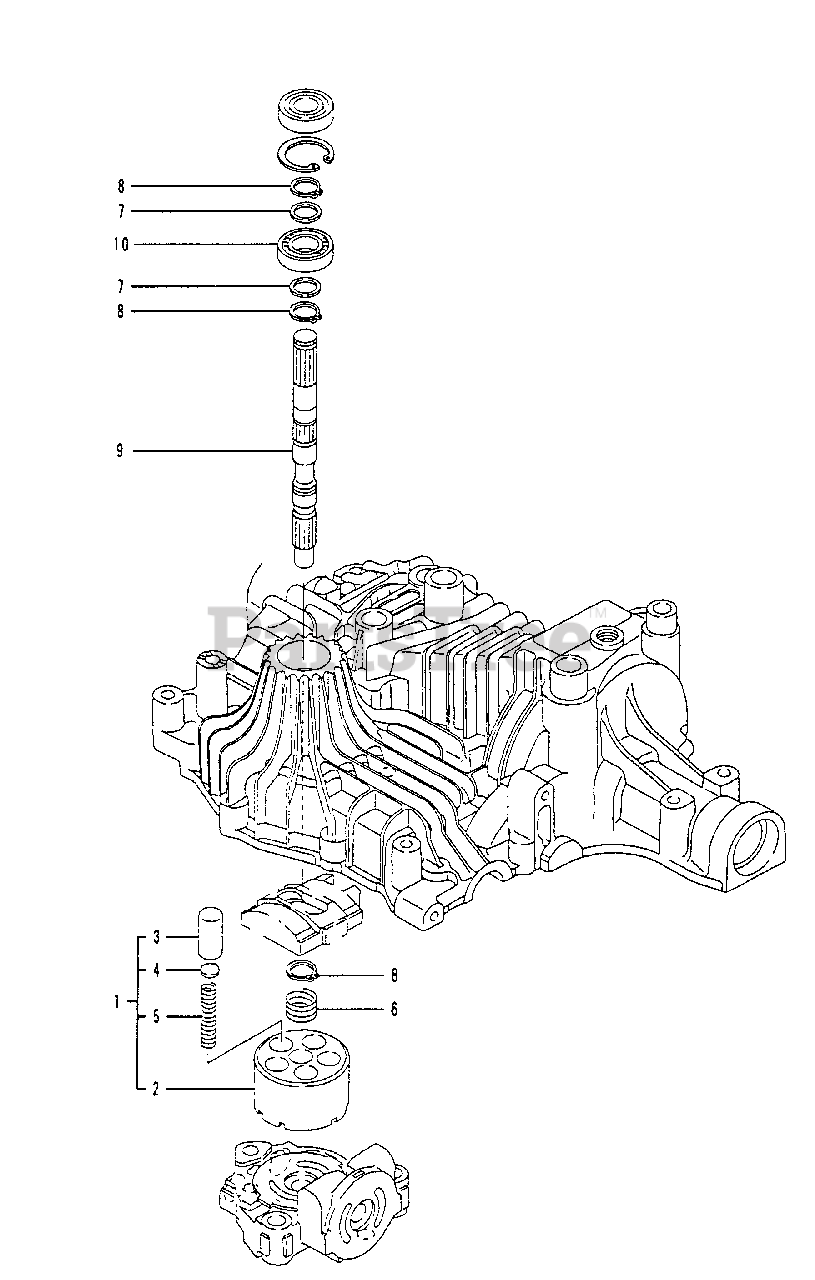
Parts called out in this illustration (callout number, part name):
1	CYLINDER BLOCK CMP
2	CYLINDER BLOCK
3	PISTON
4	WASHER 11
5	SPRING (PISTON
7	WASHER 15 x 20 x 1
10	BEARING 6202C3
